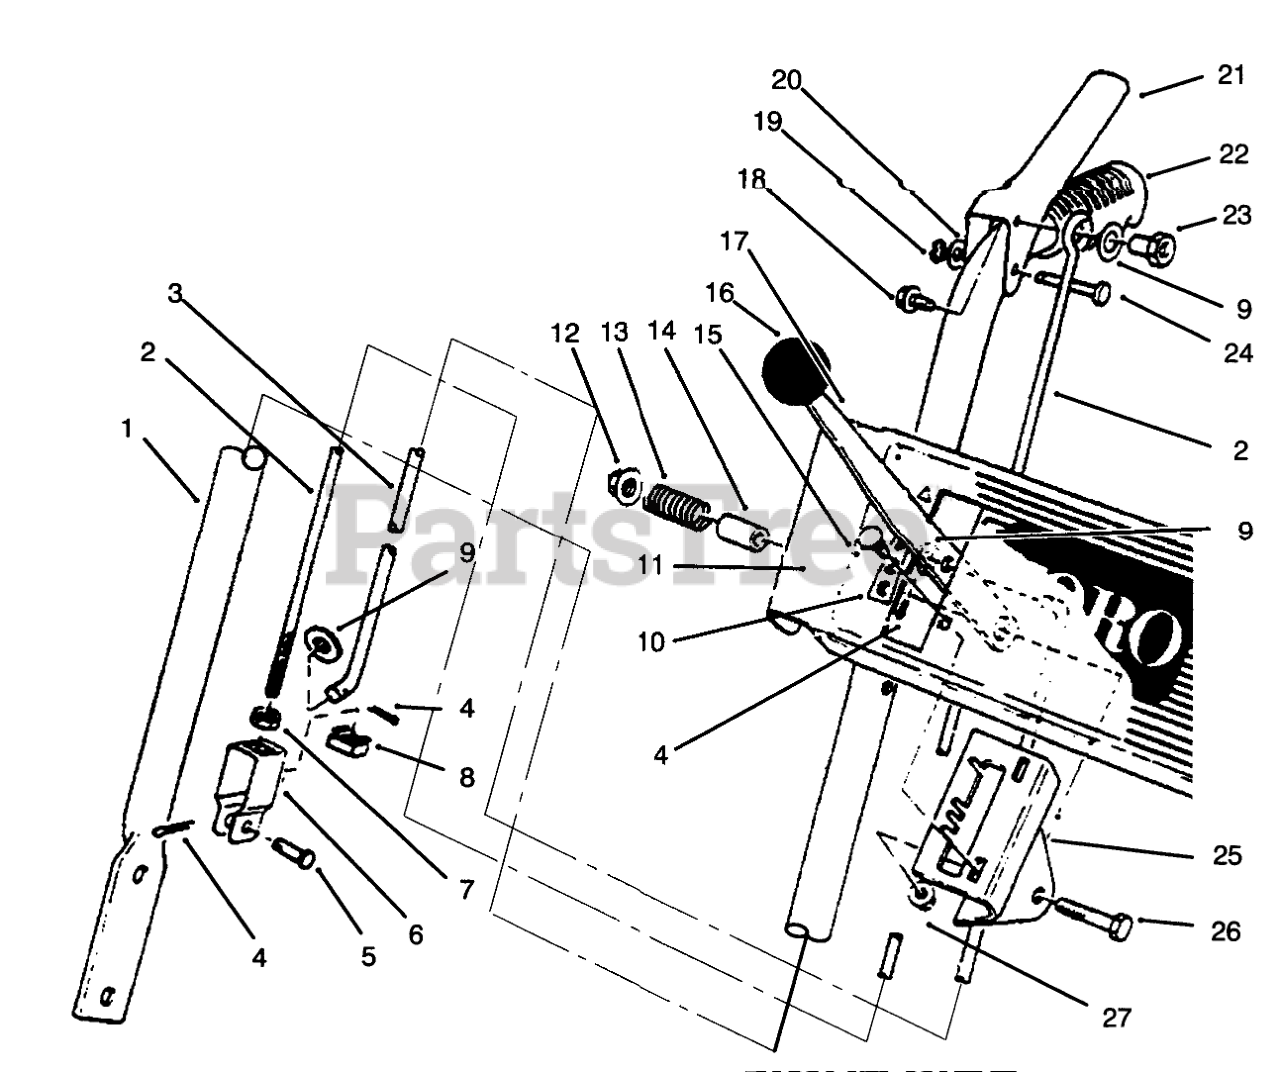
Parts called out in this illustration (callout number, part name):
1	Handle-Right
2	LINK-UPPER
3	ROD-SELECTOR, SPEED
4	PIN-COTTER
5	PIN-CLEVIS
6	CLEVIS
7	NUT-JAM
8	NUT-RETAINED
9	WASHER-PLAIN
10	ESCUTCHEON PLT B
11	DECAL ESCUTCHEON
12	NUT-HF
13	SPRING
14	SPACER
15	SCREW-CARR
17	SPEED SELECTOR B
18	SCREW-HHF
19	RING-CLIP
20	WASHER-FLAT
21	HANDLE-CONTROL
22	GRIP-HANDLE
23	POST-MOUNTING, LINKAGE
24	PIN-LEVER, CONTROL
25	Mount-Speed Selector
26	SCREW-HH
27	NUT-HF
